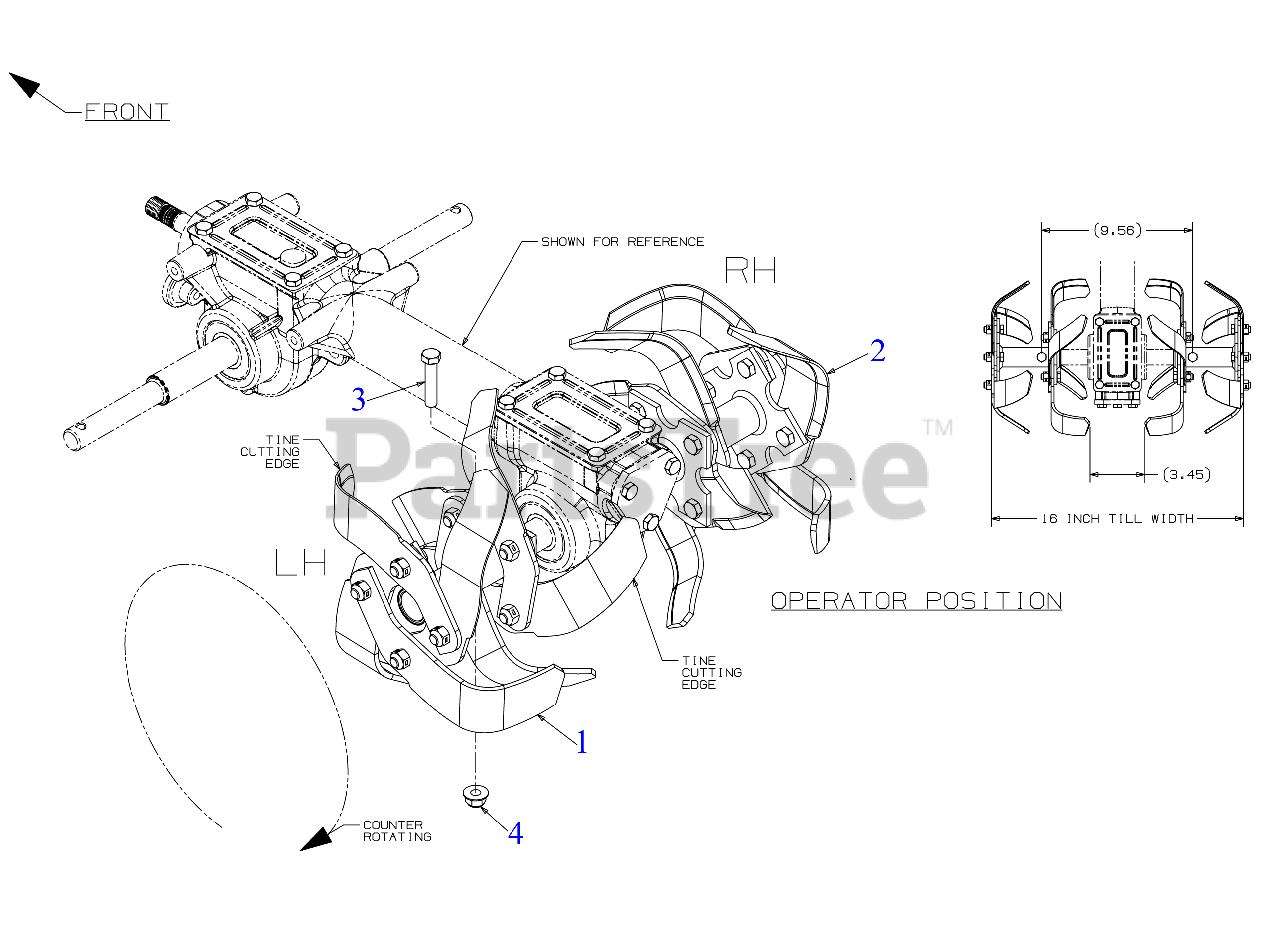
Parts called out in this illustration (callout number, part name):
1	SCREW 3/8-16 x 1 GR5
1	LOCK NUT 3/8-16
2	SCREW 3/8-16 x 1 GR5
2	LOCK NUT 3/8-16
3	HEX SCREW 3/8-16 x 1.75 GR5
